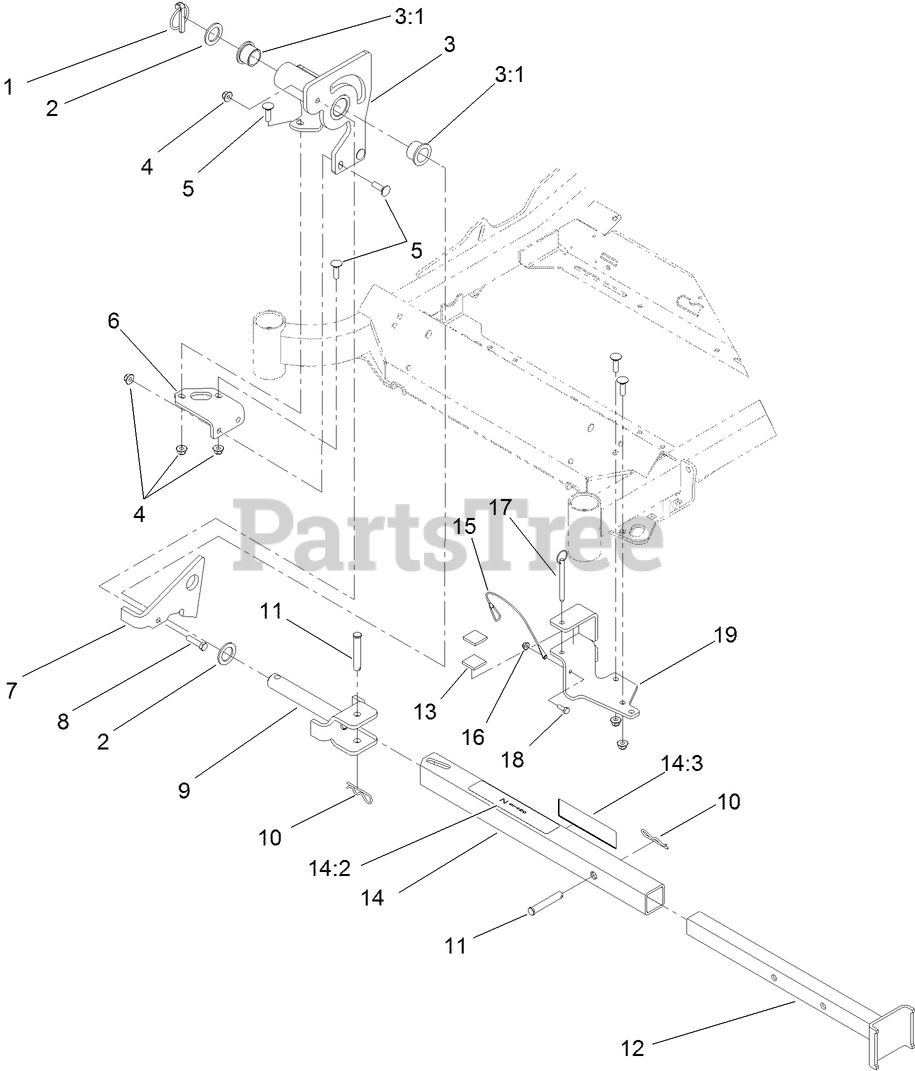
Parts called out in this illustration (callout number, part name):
1	PIN-LYNCH
2	WASHER-THRUST
3	Z STAND PIVOT ASM
3:1	BUSHING
4	NUT-HF, NI
5	BOLT-CARR
6	BRACKET-MOUNT, PIVOT
7	BRACKET-LATCH
8	SCREW-HH
9	PIN-PIVOT
10	PIN-HAIR
11	PIN-CLEVIS
12	TUBE-INNER
13	CUSHION-RUBBER
14	OUTER TUBE ASM
14:2	DECAL-Z STAND
14:3	DECAL-WARNING
15	LANYARD-NYLON
16	NUT-HF
17	PIN-HITCH, COTTERLESS
18	SCREW-HH
19	CRADLE-Z STAND
